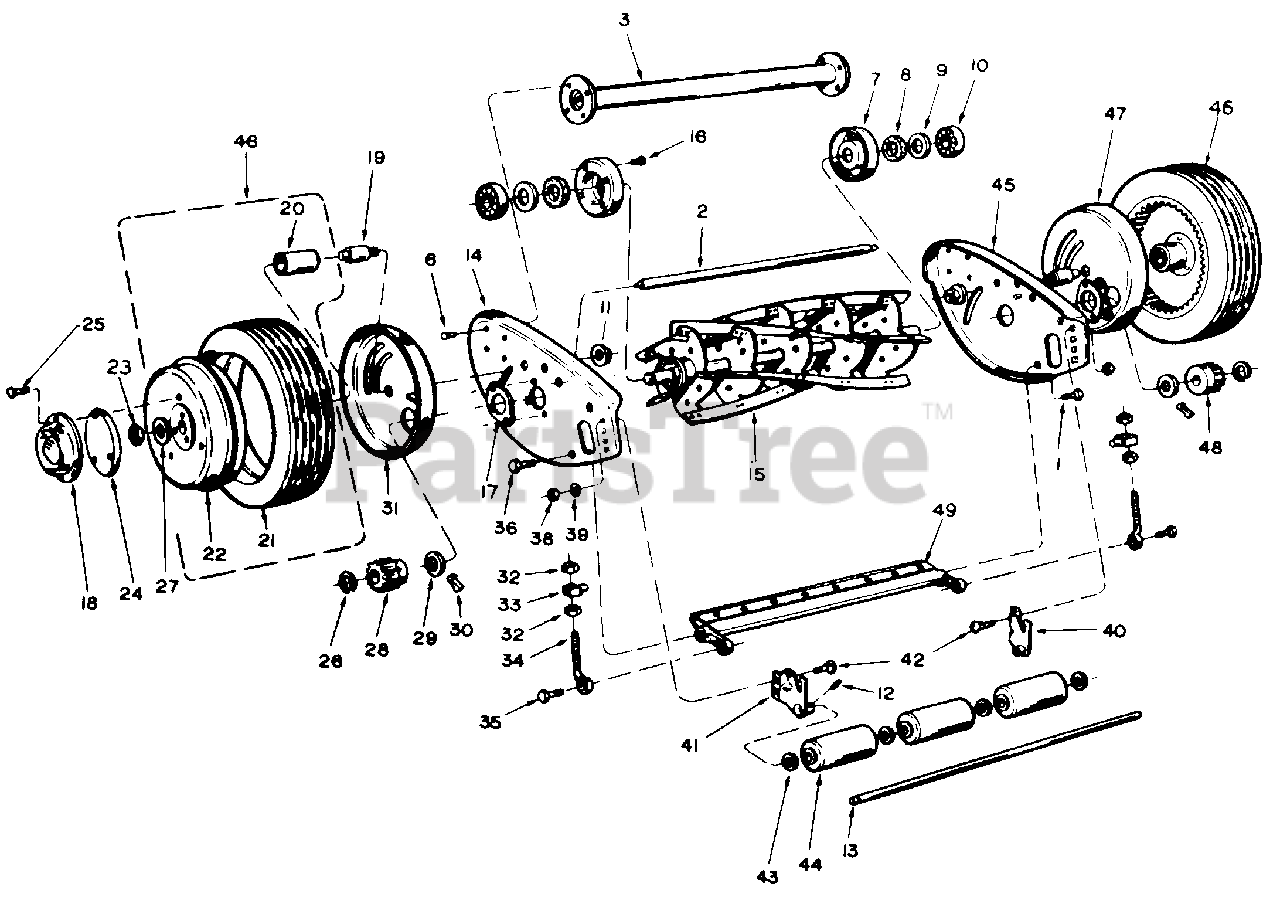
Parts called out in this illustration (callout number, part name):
1	Screw Front L.H. Thd.
2	Spacer End Plate
3	Spacer Tube Ass'y.
6	Rivet 3/16 x 3/8 Rd. Hd.*
7	Retainer
8	Felt Washer
9	Felt Retainer
10	Bearing
11	Nut-Special
12	Roll Pin
13	Roller Shaft
14	End Plate Trunnions-L.H.
15	Reel Ass'y.-21"
16	Rivet 3/16 x 13/32 Rd. Hd.*
17	Bearing Retainer
18	Hub Cap
20	Bearing
21	Ti re
22	Drive Wheel-Less Tire
23	Retaining Ring
24	Wheel Weight
25	Scr. #10-32 x 1 3/8 Thd. Cutting
26	Retaining Ring*
27	Washer
28	Pinion Gear-L.H.
29	Felt Washer
31	Gear Housing-L.H.
32	Hex Nut 3/8-24 Semi Fin*
33	Trunnion
34	Cutter Bar Adjusting Bolt
35	Screw-Rear
36	Screw-Front R.H. Thd.
38	Nut 5/8-18*
39	L. Wash. 5/16" I.D.*
40	Roller Brkt.-R.H.
41	Roller Brkt.-L.H.
42	Carr. Bolt 5/16-18 x 1*
43	Washer 1/2 x 1 1/16*
44	Roller
45	End Plate with Trunnions-R.H.
46	Drive Wheel Ass'y. Wire
47	Gear Housing-R.H.
48	Pinion Gear-R.H.
49	Cutter Bar Ass'y.
